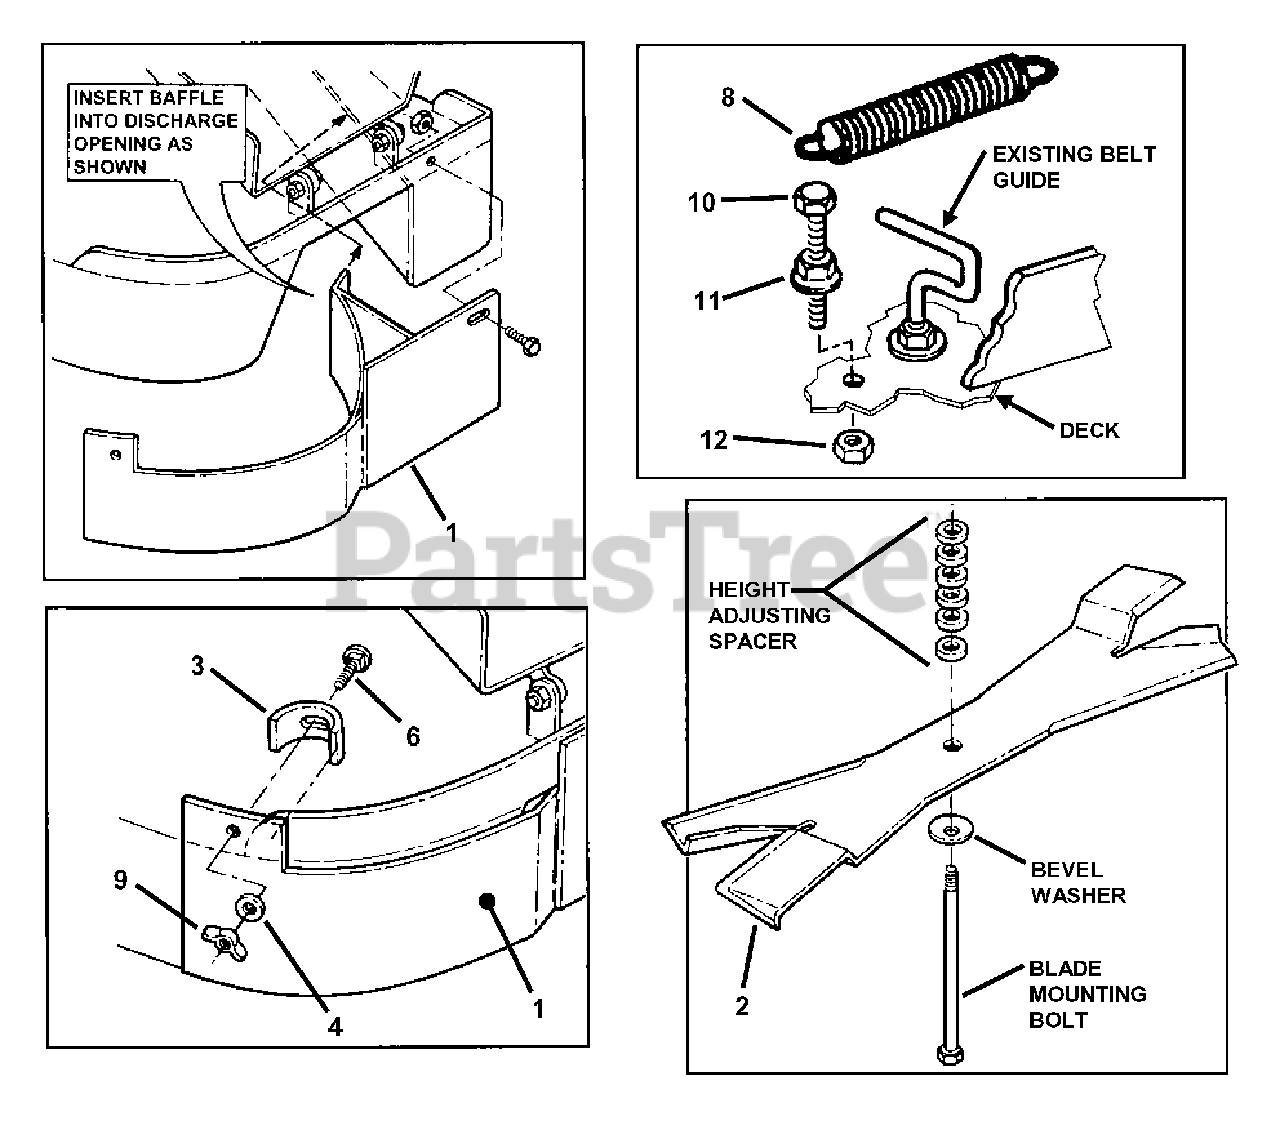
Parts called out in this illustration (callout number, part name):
1	WELDMENT, 36" Recycling Baffle
2	BLADE, 18" Quad Edge
3	CLAMP
4	WASHER, 5/16" Flat
5	NUT, 1/2-20 Hex Jam
6	BOLT, 5/16-18 x 1-1/2" Square Neck Carriage, Grade 5
7	BOLT, 1/2-20 x 3/4" Hex Washer Face w/Nylon Patch, Grade 5
8	SPRING, Idler Return
9	KNOB, 5/16-18 Wing
10	SCREW, 5/16-18 x 1-1/2" Hex Head Cap
11	NUT, 5/16-18 Hex Flange Lock
12	NUT, 5/16-18 Hex Nyloc
